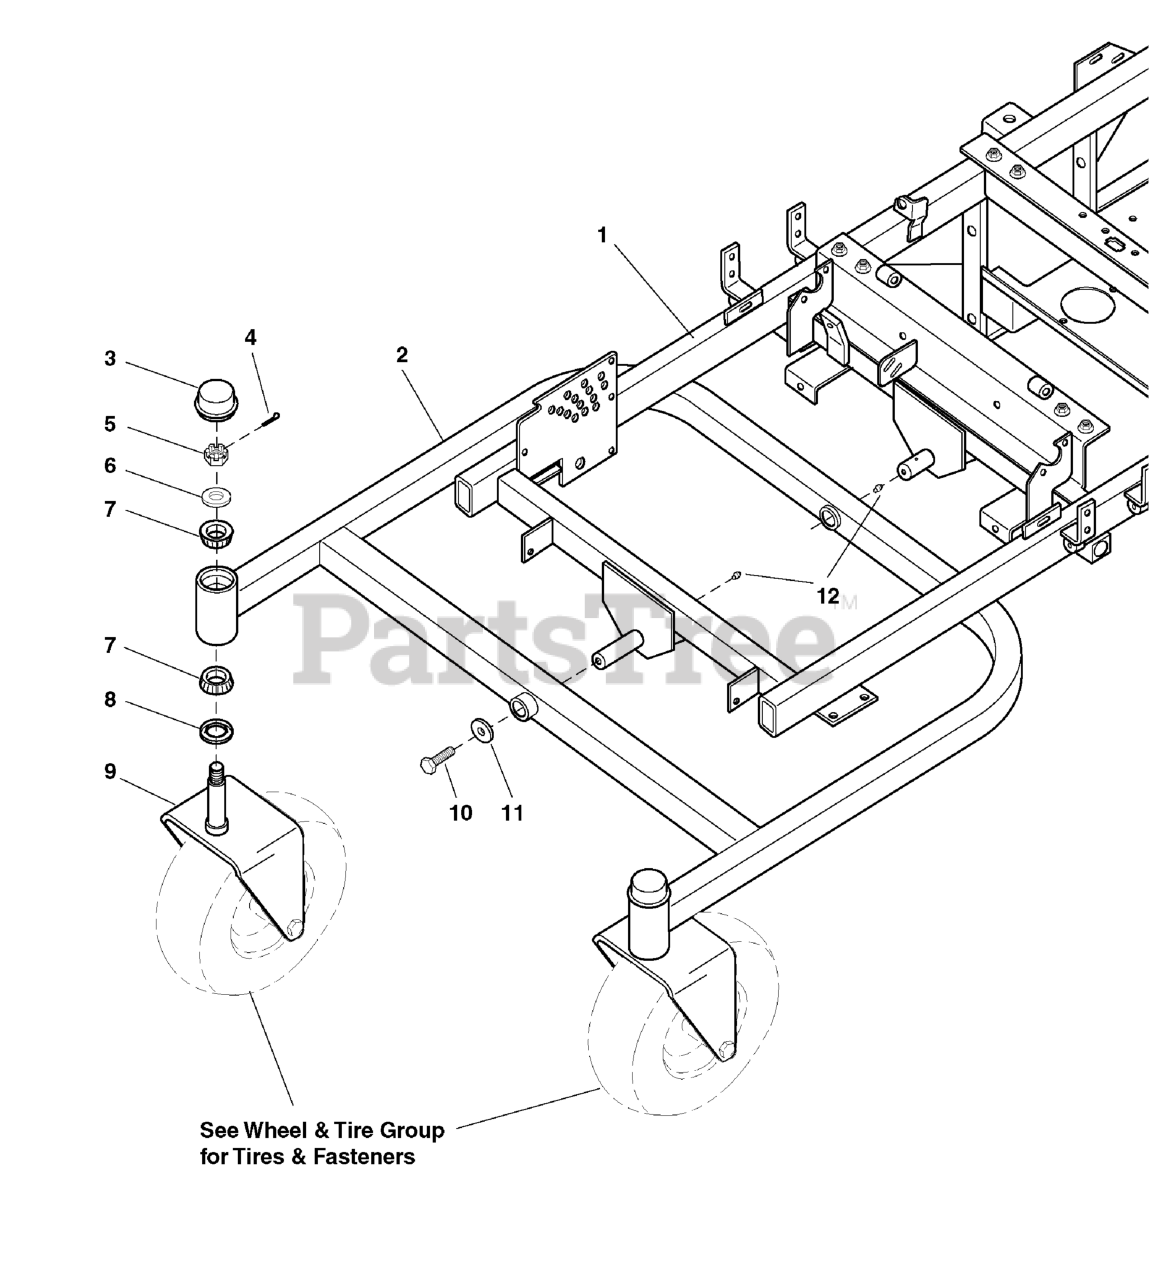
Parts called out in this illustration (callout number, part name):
1	MAIN FRAME
2	FRAME, Front Pivot
3	CAP
4	PIN, COTTER, 1/8 X 1-1/4
5	NUT, 3/4-16 Hex Slotted
6	WASHER, 3/4 SAE
7	BEARING, Tapered Roller
8	SEAL, GREASE
9	YOKE, Caster
10	BOLT, 1/2-20 X 1-1/4" GD5 CZ
11	WASHER, Frame Retaining
12	GREASE FITTING
